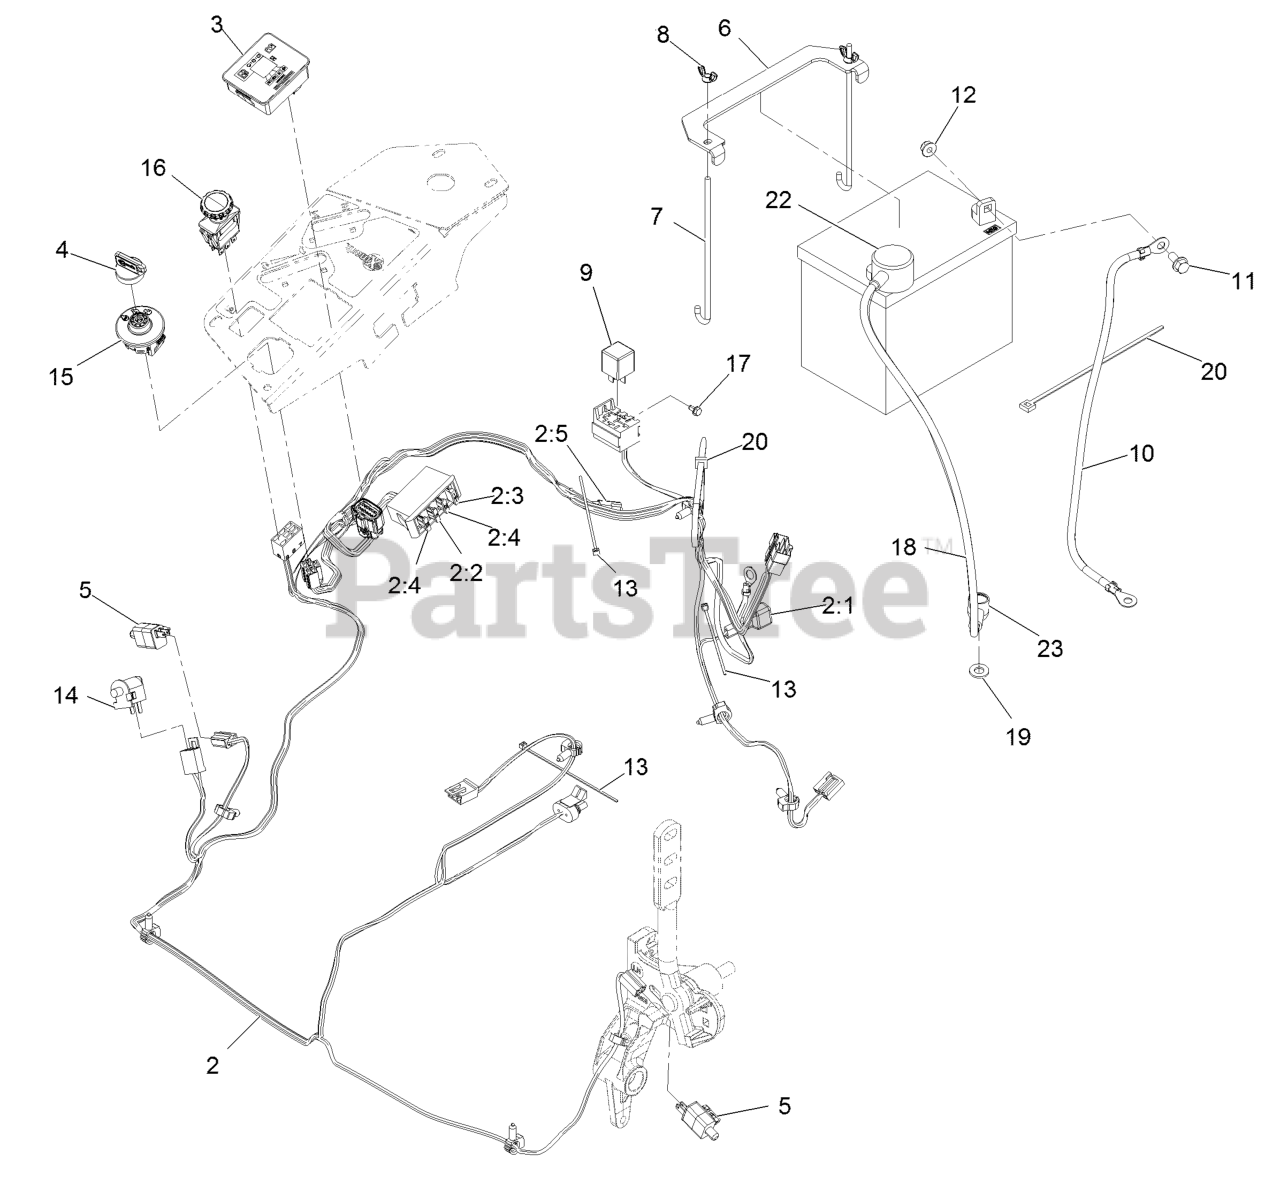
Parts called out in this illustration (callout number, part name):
2	Harness-Wire, Main
2:2	Fuse-Blade, 10 Amp
2:3	Fuse-Blade, 15 Amp
2:4	Fuse-Blade, 25 Amp
2:5	Cap-Plug
3	Fuel/Hour Meter ASM
4	Key-Ignition
4	Key-Exmark Logo
6	Strap-Tie Down, Battery
7	Bolt-Holddown
8	Wingnut-Nyloc 1/4-20
9	Relay-12Vdc 40 Amp
10	Cable-Battery, Negative
11	Screw-HH Flg 5/16-18 X 3/4
12	Nut-Nyloc 5/16-18 Flg
13	Tie-Cable 5 1/2 (Small)
15	Switch-Ignition
16	Switch-PTO, 10 Amp
17	Screw-HWH #10-24 X 3/8
18	Cable-Battery, Positive
19	Washer-3/8 Sae
20	Tie-Cable 7 15/16 (Large)
22	Insulator-Battery
23	Insulator-Solenoid
